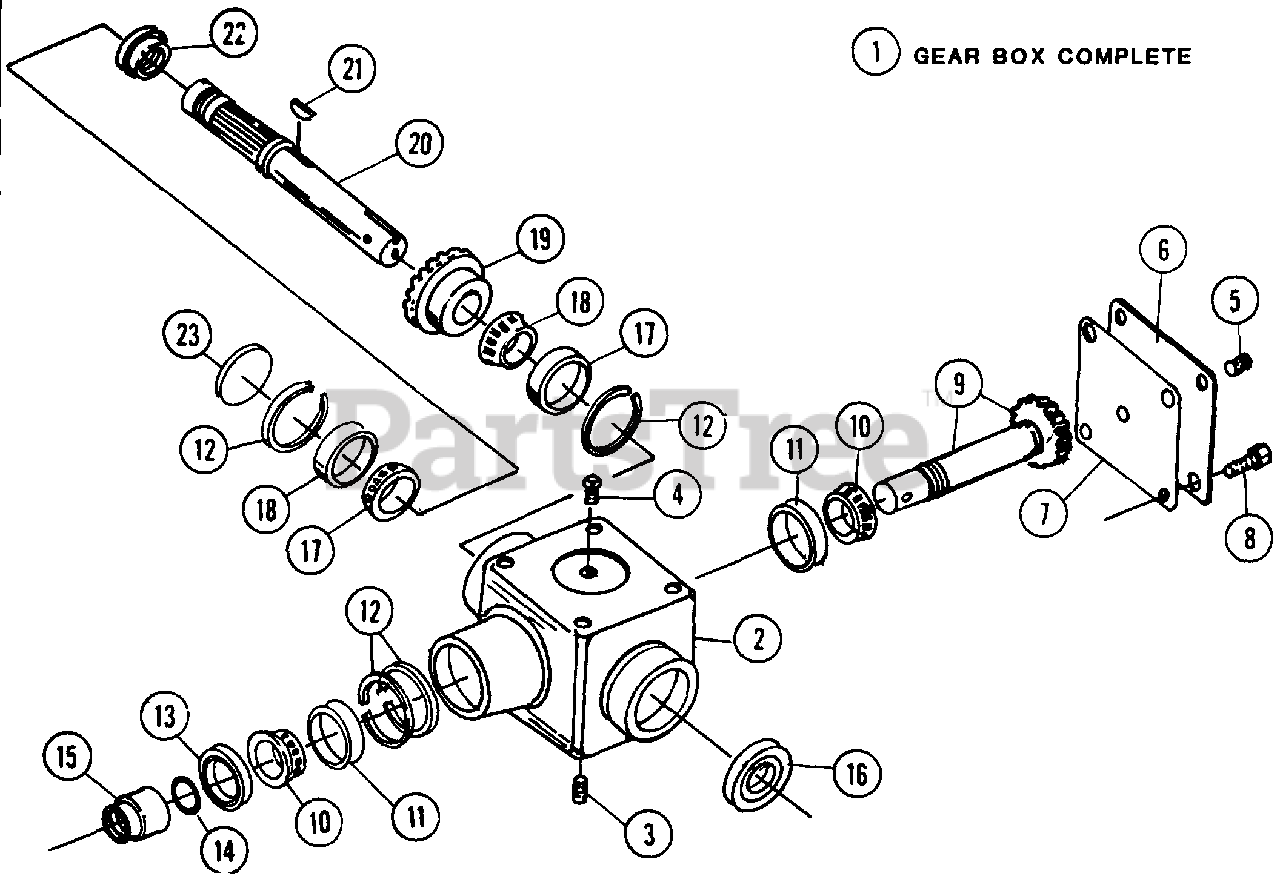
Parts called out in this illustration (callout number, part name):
1	GEAR BOX, 2:1 RATIO Durst #4465
2	HOUSING, GEAR BOX
3	PLUG, DRAIN 3/8-18 NPT
4	PLUG, VENT 3/8-18 NPT SQUARE HEAD
5	PLUG, CHECK 1/8-27 NPT
7	GASKET, COVER
8	HHCS, 5/16C X5/8 GR5 ZP
9	SHAFT, BEVEL PINION
10	BEARING CONE
11	BEARING CUP
12	RING, RETAINING
13	SEAL, OIL VICTOR #64494
14	O-RING, NS 122
15	STAKE-NUT
16	SEAL, OIL
17	BEARING CUP
18	BEARING CONE
19	GEAR, BEVEL 32T - 10P
20	SHAFT, OUTPUT
21	KEY, WOODRUFF (A 807 HARD)
22	STAKE-NUT
23	CAP, END
